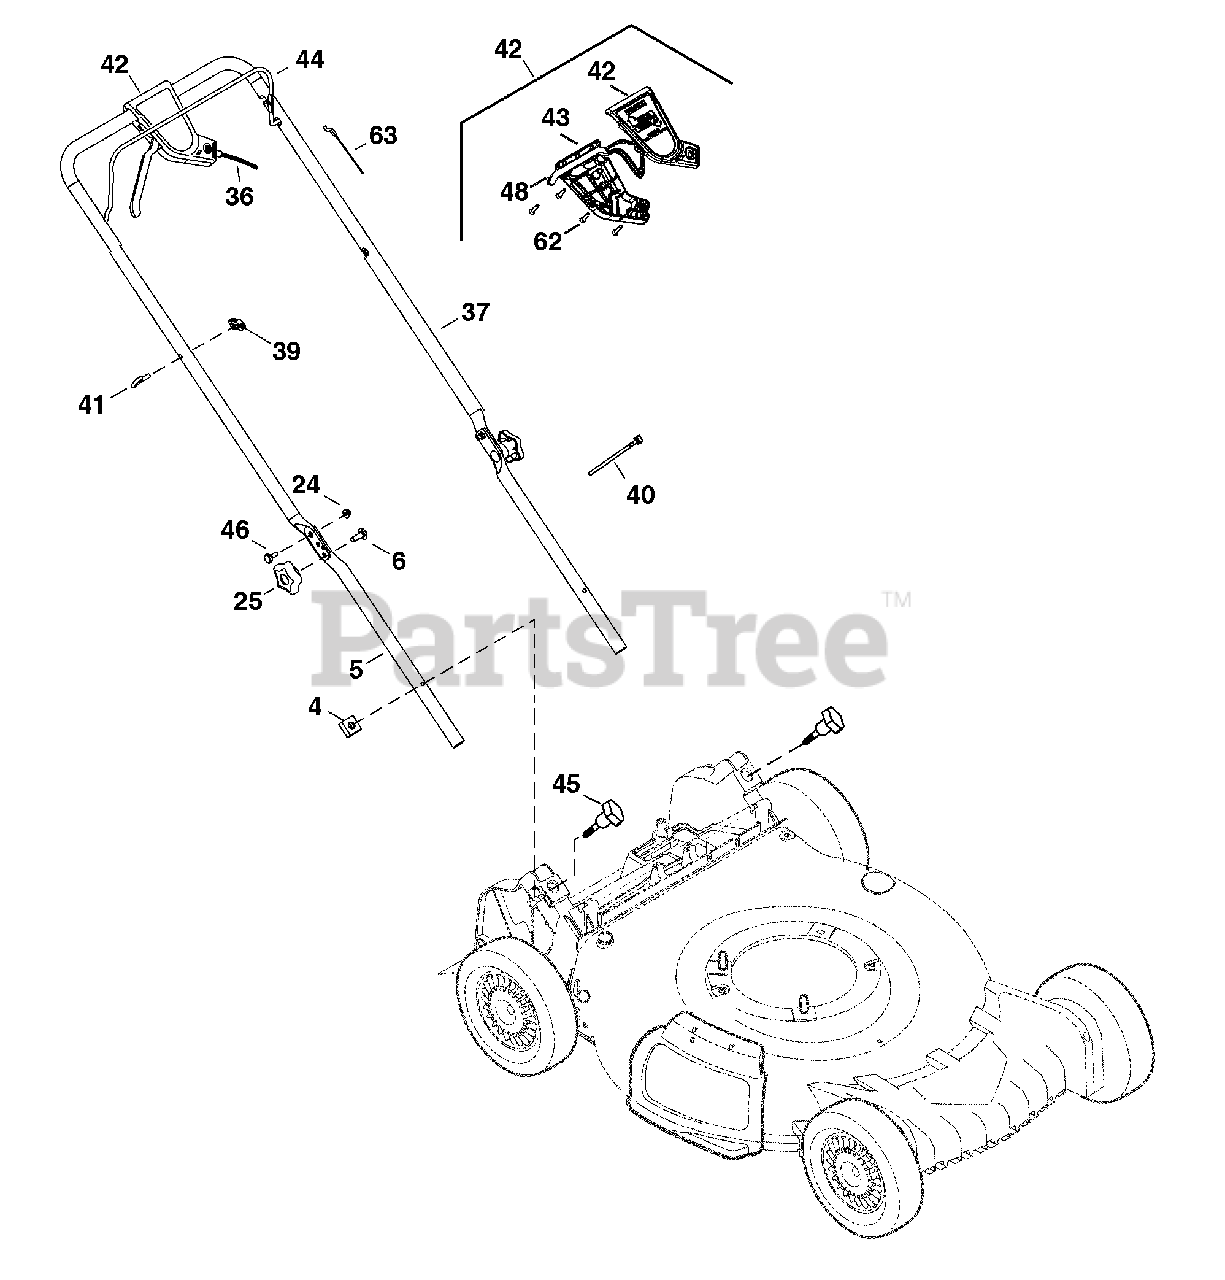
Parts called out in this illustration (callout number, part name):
4	NUT, Square, 1/4-20
5	HANDLE, Lower
6	BOLT, Carriage, 5/16-18 X 1, GR5
24	NUT, Nylock Flanged, 1/4-20
25	KNOB, Handle, 5/16-18
36	CABLE, Control, Variable Speed
37	HANDLE, Upper, Adjustable
39	KNOB, 1/4-20
40	TIE, Self Locking, 15" Long
41	GUIDE, Rope
42	ASSEMBLY, Control Lever
43	Control Cover Lower
44	Operator Bail Assembly
45	NUT, Wing
46	BOLT, Shoulder, 1/4-20
48	Engagement Lever
62	SCREW, #10-16 X 1.00
63	CABLE, OPC Engine Brake
